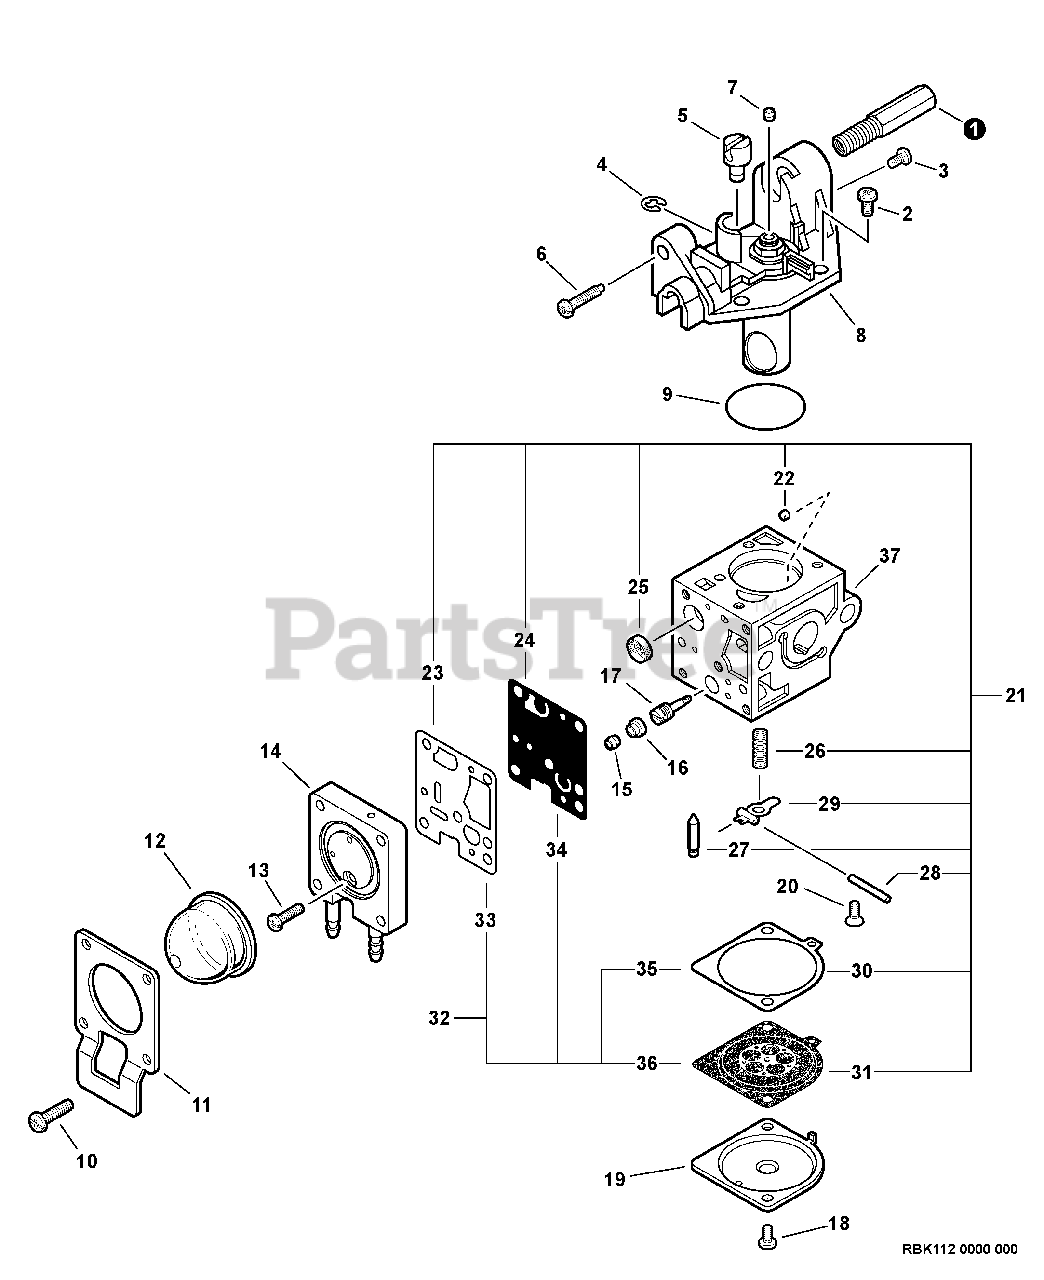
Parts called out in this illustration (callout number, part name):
1	GASKET KIT
2	GASKET, CRANKCASE
3	GASKET, CYLINDER
4	HEAT SHIELD, INTAKE
5	GASKET, INTAKE
6	HEAT SHIELD, EXHAUST
7	GASKET, EXHAUST
8	TUNE-UP KIT - REPOWER
9	PRE-FILTER, FOAM
10	FILTER, AIR - DOUBLE LAYER
11	FILTER, FUEL
12	SPARK PLUG - BPMR8Y
13	FUEL SYSTEM KIT - REPOWER
14	VENT ASSY
15	CLIP 6.5MM
16	PIPE, VENT 3×6×35 BLACK
17	PIPE, FUEL 3×5×195 BLACK
18	PIPE, FUEL 3×6×75 CLEAR
19	GROMMET, FUEL
21	FILTER, FUEL 125-528
22	FUEL SYSTEM KIT - REPOWER
23	VENT ASSY
24	CLIP 6.5MM
25	PIPE, VENT 3×6×35 BLACK
26	PIPE, FUEL - 3×5×67 - BLACK
27	PIPE, FUEL 3×6×75 CLEAR
28	GROMMET, FUEL
29	CONNECTOR, PIPE 5×3.5
31	PIPE, FUEL - 3×5×125 - BLACK
32	FILTER, FUEL 125-528
33	GASKET, FUEL CAP
34	CAP/VENT KIT - REPOWER
35	CAP, FUEL
36	VENT ASSY
37	GASKET, FUEL CAP
38	PIPE, BULK - REPOWER 3×5mm BLACK
39	PIPE, BULK - REPOWER 3×6mm CLEAR
40	PIPE, BULK - REPOWER 3×6mm BLACK
41	ROPE, STARTER - REPOWER BULK 3
